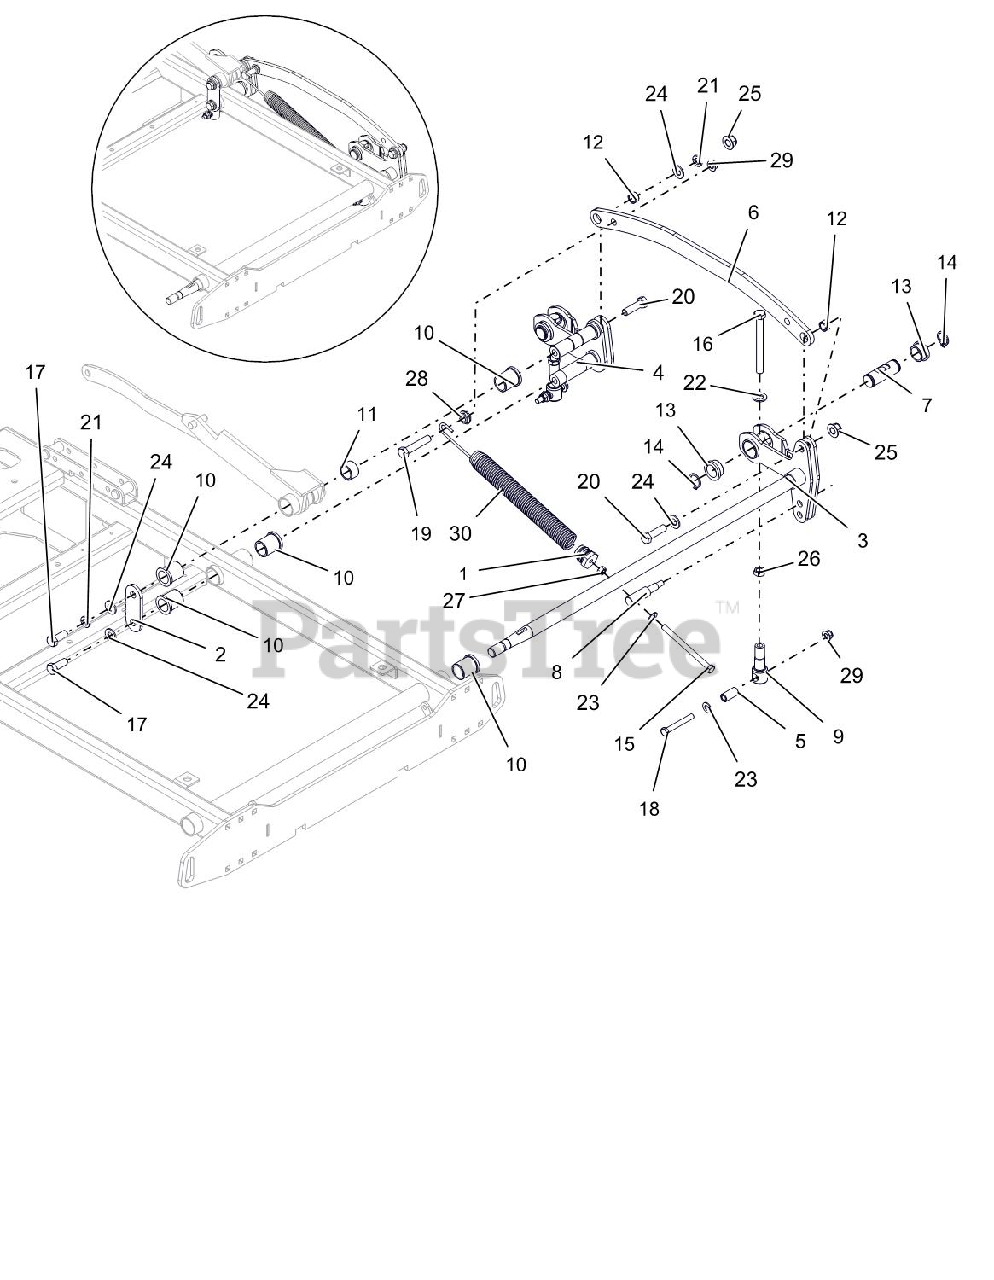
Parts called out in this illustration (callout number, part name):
1	PLUG, SPRING
2	PLATE, LIFT LINK ATTACH
3	WLDMT, PSTANCE TAPERED SHAFT
4	WLDMT, PSTANCE DECK ARM
5	SPACER, DECK LEVELING
6	ARM, DECK LIFT
7	PIN, DECK LIFT
8	TRUNION, DECK LIFT
9	LINK, DECK LIFT FORMED
10	BSHG-FLG 1.00X1.25X1.50X1.50
11	BUSH, SLV 1.00 X 1.25 X .75
12	BSHG-SLV .513 X .748 X .420
13	BSHG,FLG 1.0 X 1.25 X 1.5 X .6
14	RG-RTNG-EXT 1.00X.078
15	BLT-HEX .38-16X5.00 GR5 FTH YZ
16	BOLT, 1/2-13 X 5.0 2.5 THREAD
17	@BLT-HEX .50-13X1.25 GR5 YWZC
18	BLT-HEX .38-16X2.75 GR8 YWZC
19	@BLT-HEX .50-13X2.50 GR5 YWZC
20	@BLT-HEX .50-13X1.75 GR5 YWZC
21	@WSHR-LK .50X.125 REG YWZC
22	FLATWASHER 1/2 SAE HARD 15906
23	@WSHR-FL-STL.406X.812X.065 YWZ
24	@WSHR-FL-STL.531X1.06X.095YWZC
25	@NUT-LK-NYL-FLG .50-13 YWZC
26	NUT-JAM .50-13 YWZC
27	@NUT-HEX .38-16 YWZC
28	NUT-SPNLK-FLG .50-13 YWZC
29	@NUT-LK-NYL-FLG .38-16 YWZC
30	SPRING, DECK LIFT
